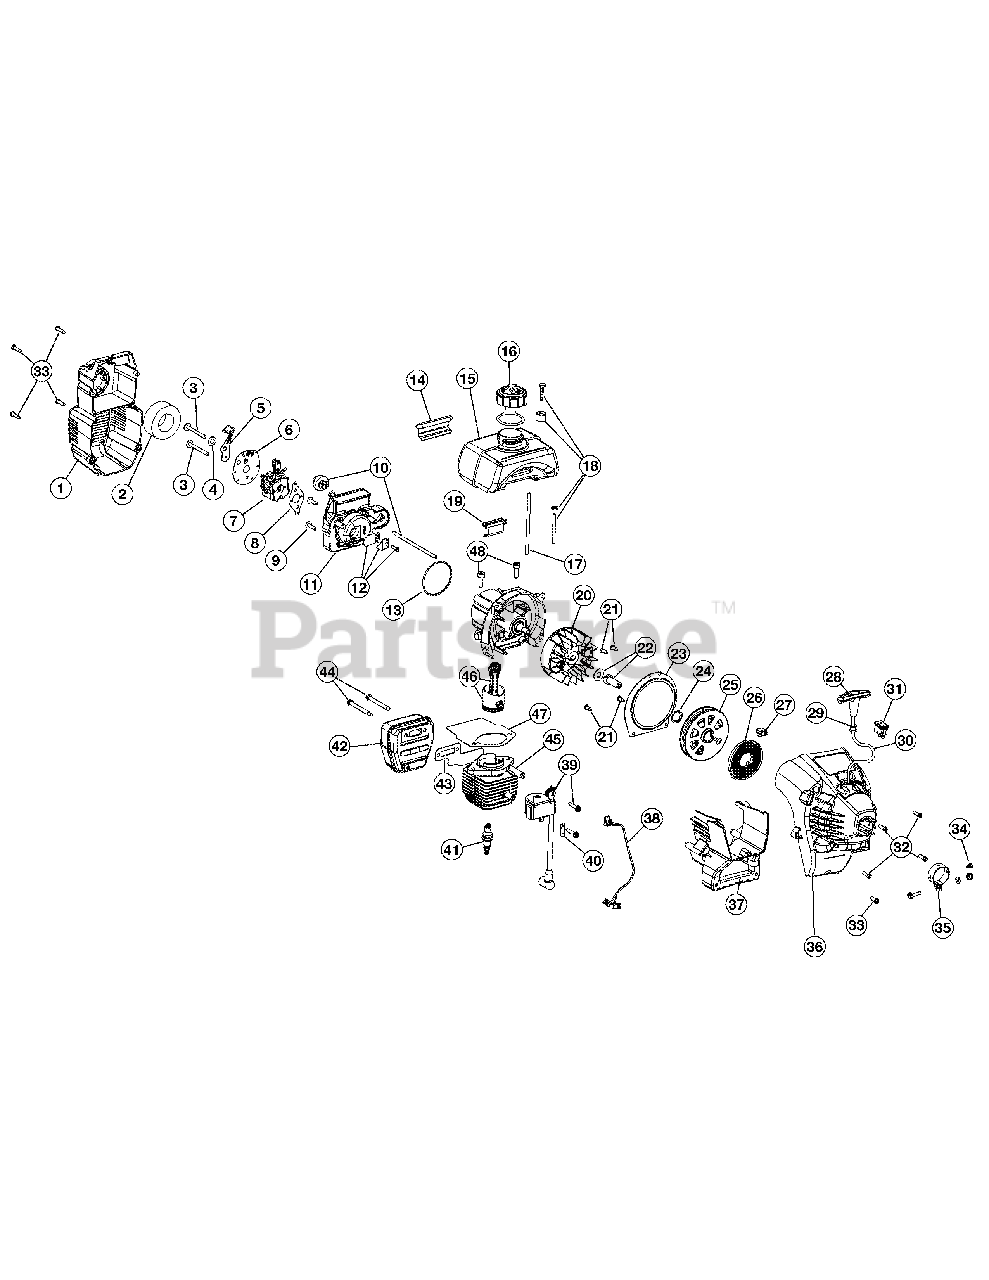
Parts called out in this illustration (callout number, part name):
1	Air Cleaner Cover Assembly
2	Air Cleaner Filter
3	Carburetor Mounting Screws
4	Wavey Washer
5	Choke Lever Assembly
6	Choke Lever & Plate
7	Carburetor Assembly
8	Carburetor Gasket
9	Carb Mount Screw
10	Primer & Hose Assembly
11	Carburetor Mount Assembly
12	Reed Assembly
13	O-Ring
14	Rear Mounting Pad
15	Fuel Tank Assembly
16	Fuel Cap Assembly
17	Fuel Return Line
18	Fuel Line Assembly
19	Front Mounting Pad
20	Flywheel Assembly
21	Plate Screw
22	Square Nut Drive
23	Pressure Plate
24	Palnut
25	Recoil Pulley Assembly
26	Recoil Spring
27	Eyelet Retainer
28	Pull Handle
29	Rope Guide
31	Switch Assembly
32	Housing Screw
33	Cover Screw
34	Anti-Rotation Screw
35	Clamp Assembly
36	Starter Housing Assembly
37	Shroud Extension & Stand
38	Wire Lead
39	Module Assembly
40	Ground Tab
41	Spark Plug
42	Muffler Assembly
43	Exhaust Gasket
44	Muffler Mouting Bolt Assembly
45	Cylinder Assembly
46	Piston & Rod Assembly
47	Cylinder Gasket
48	Cylinder Bolt
